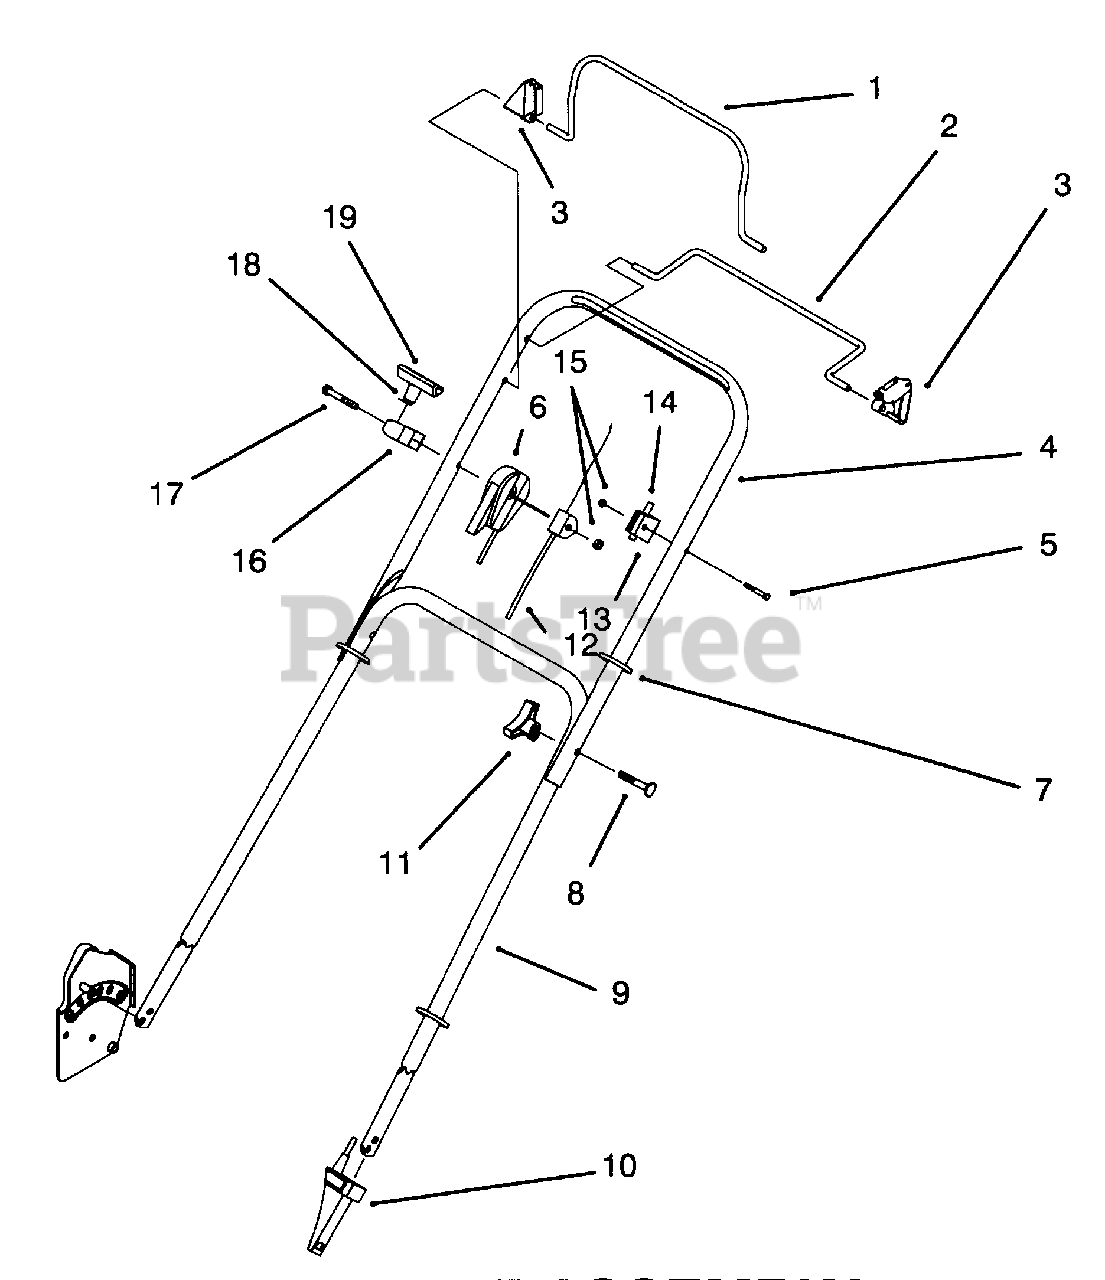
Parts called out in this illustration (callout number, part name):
1	Bail-Flywheel Brake
2	Bail-SP Control
3	Stop-Pivot
4	Handle-Upper
5	Screw-Handle
6	Cable-Throttle
7	Tie-Cable
8	Screw-Handle
9	Handle-Lower
10	Anchor-Cable SP Lower
11	Knob
12	Cable-Brake
13	Anchor-Cable SP Upper
14	Cable-Traction
15	Nut-Lock
16	Guide-Rope
17	Screw-Hex Hd. Cap
18	Handle-Starter
19	Staple-Handle
